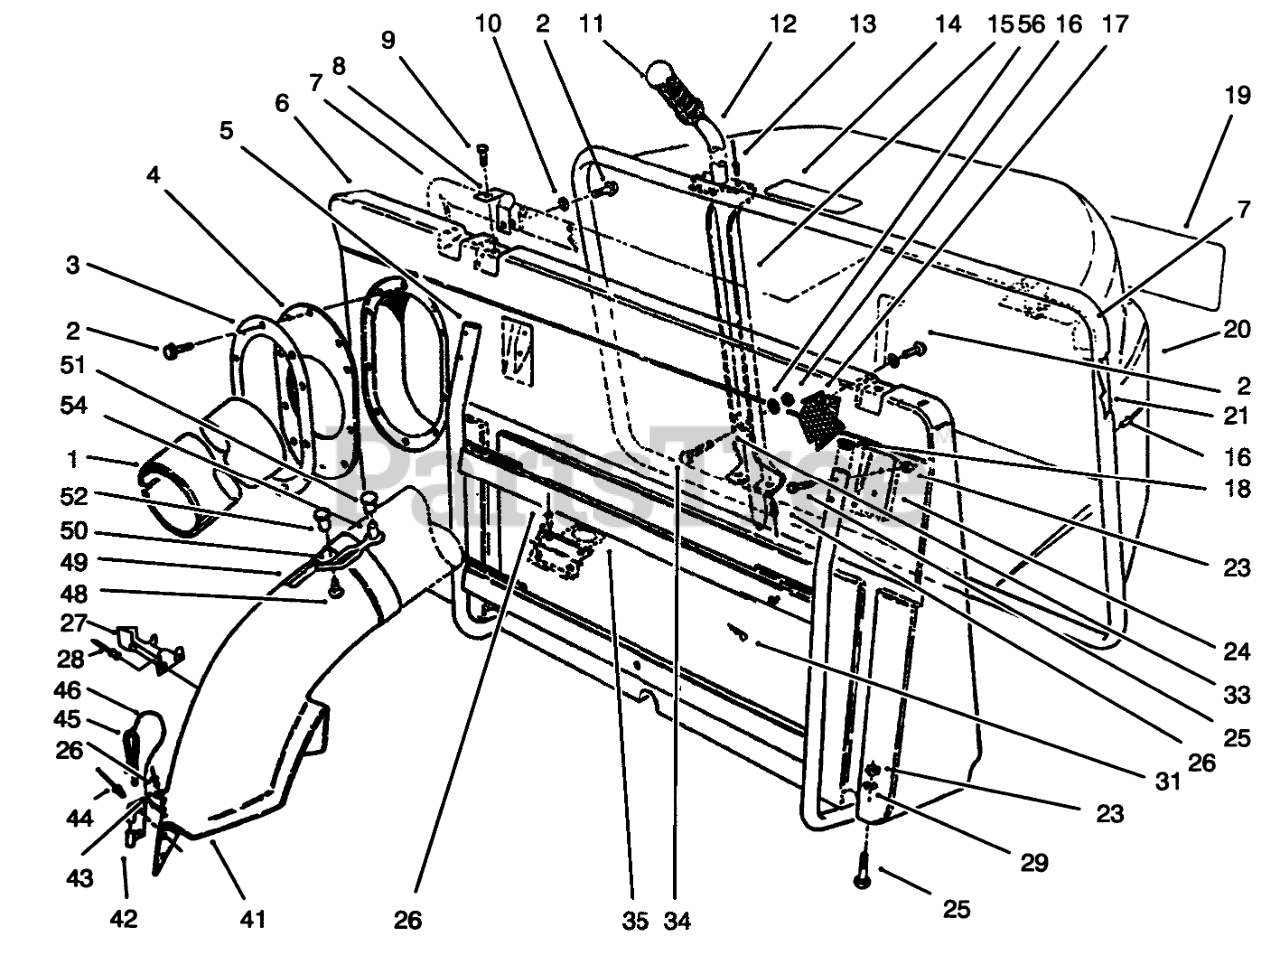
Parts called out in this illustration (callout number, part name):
1	GRASS DISCHARGE TUBE
2	Screw
3	RING-RETAINING
4	RING-RETAINER, RUBBER
5	Frame
6	BAG-FRONT
7	SEAL-BAG
8	Bracket-Hinge
9	SCREW-HH
10	WASHER-FLAT
11	GRIP-HANDLE
12	HANDLE-DUMP
13	RIVET-POP
14	DECAL - WARNING
15	Channel-Dump Handle
16	NUT-LOCK, NI
17	Screen Bag
19	DECAL-BAG, EASY EMPTY
20	BASKET-GRASS
21	Frame-Grass Basket
23	NUT-LOCK, NI
24	Plate-Backup
25	SCREW-HH
26	RIVET-BLIND
27	Latch-38"
28	RIVET-POP
29	WASHER-FLAT
31	PIN-HAIR
33	GUIDE-HANDLE, DUMP
34	SCREW-HH
35	Latch
41	CHUTE
42	BRACKET-MOUNTING, CHUTE
43	WASHER-PLAIN
44	RIVET-BLIND
45	PIN-LOCKING, CHUTE
46	LANYARD
48	SCREW-PPHTF
49	DECAL-DANGER
50	RETAINER-DUCT
51	SPACER-INTERLOCK
54	FASTENER-PANEL
56	WASHER-FLAT
